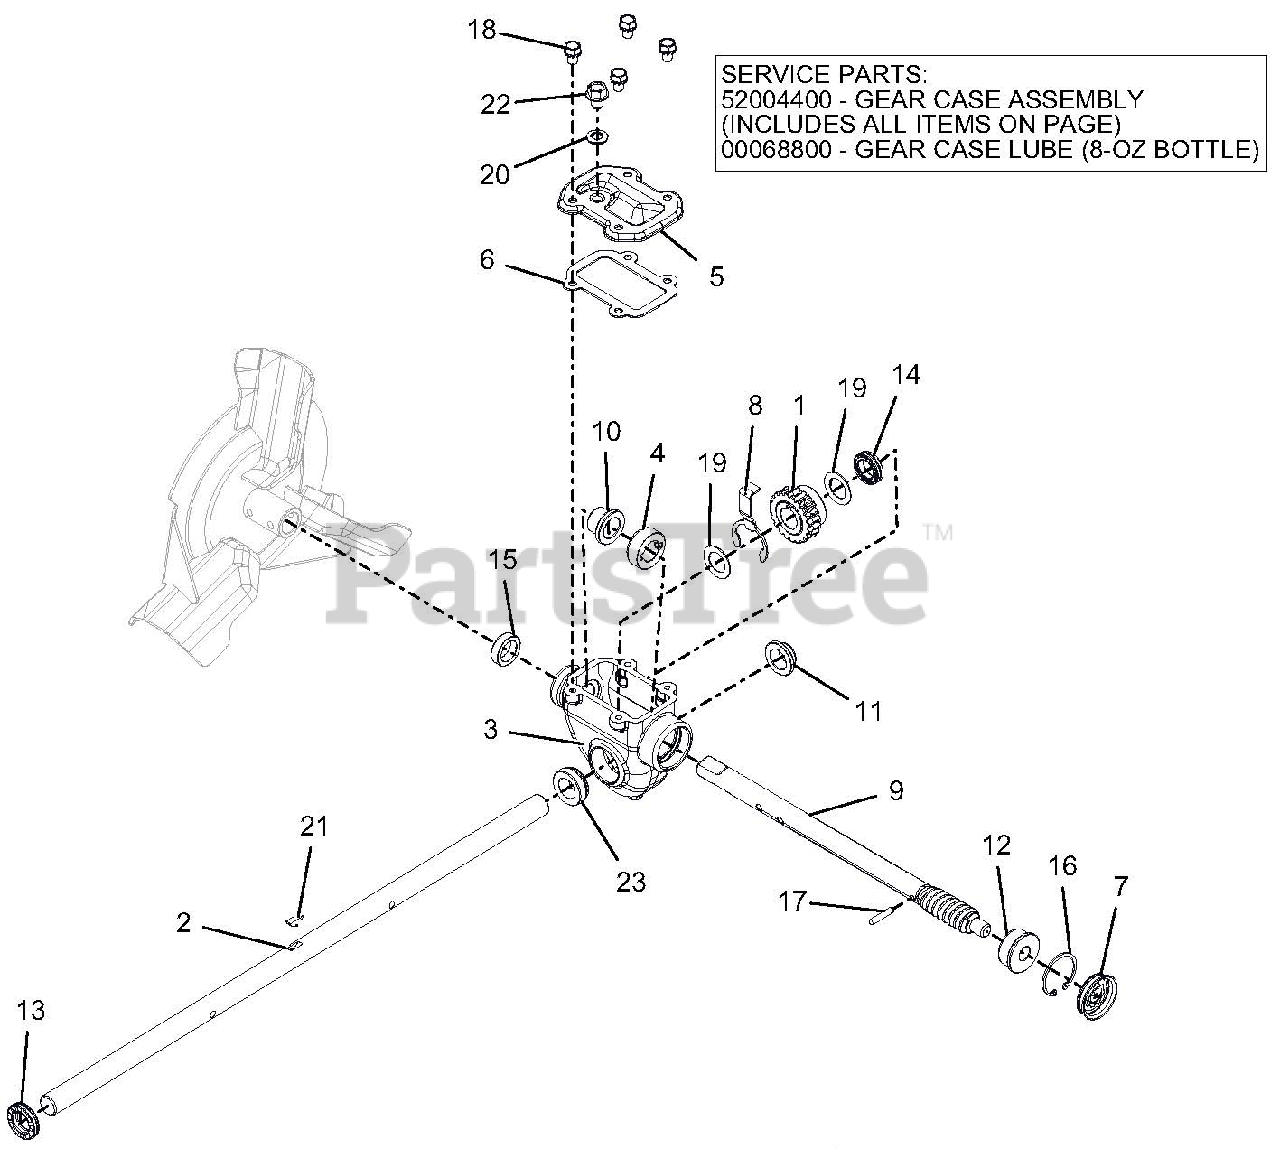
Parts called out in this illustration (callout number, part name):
1	SHAFT AND WORM GEAR ASSEMBLY
2	SHAFT, RAKE - 24" (.750 DIA)
3	GEARCASE, COMPACT MACHINED
4	THRUST COLLAR, .75" ID SLIPFIT
5	COVER, TOP - COMPACT
6	GASKET, TOP - COMPACT GEARCASE
7	COVER, GEAR CASE 1.50"
8	BUSHING RETAINER, COMPACT
9	SHAFT AND WORM GEAR ASSEMBLY
10	BSHG-FLG .755X.878X.75X1.25
11	BSHG-FLG .755X.878X.424X1.25
12	BSHG-FLG .503X1.303X.62X1.465
13	SEAL-OIL .748X1.300X.250 TBC29
14	SEAL-OIL .748X1.125X.312 TBC29
15	SEAL-OIL .748X1.125X.312 TB2-H
16	RG-RTNG-INT 1.500X.050
17	PIN-STR .188X1.00 6150
18	BOLT, SEMS .31-18X.50 GR5 YWZC
19	WSHR-FL-STL .760X1.225X.032 YZ
20	WSHR-BND-SEAL .38X.75X.11 GALV
21	KEY-WDRF .19X.63 HRD #61
22	@SCR-ROLOK .38-16X.50 HWH YWZC
23	BSHG-FLG COMPACT, RIGHT
24	GEAR CASE, 24" IRON SM TOP-LD
25	ARIENS L3 LUBE, 8 OZ BOTTLE
